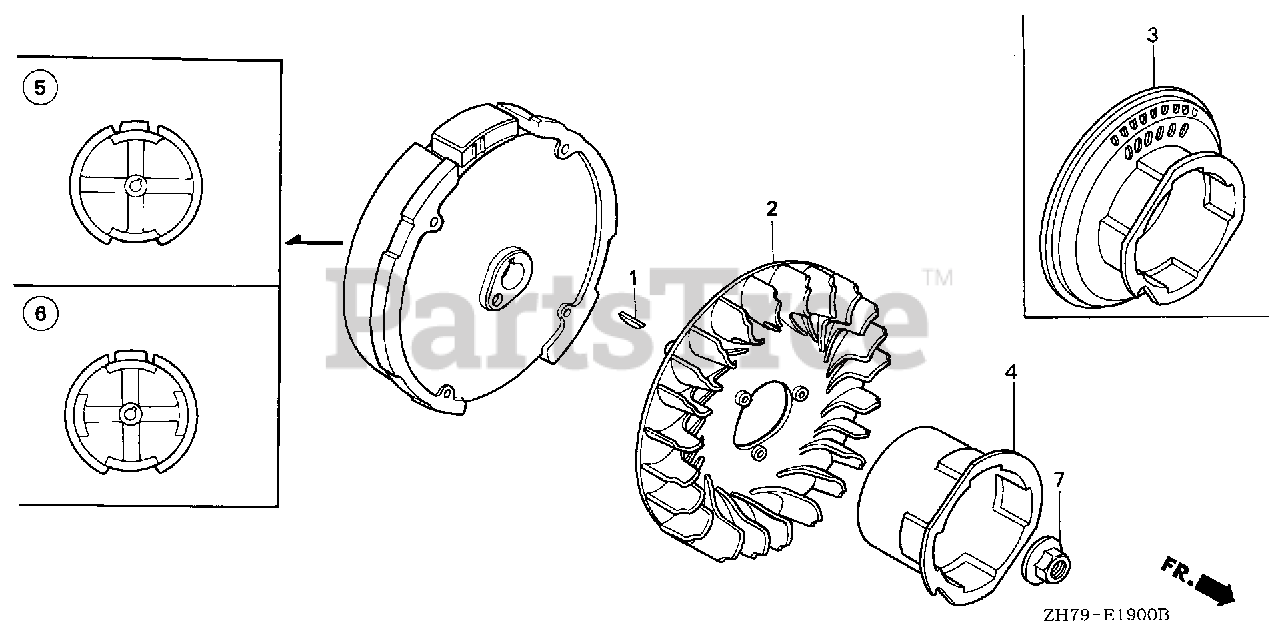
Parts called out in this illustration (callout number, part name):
1	KEY, SPECIAL WOODRUFF (25X18)
2	FAN, COOLING
4	PULLEY, STARTER
5	FLYWHEEL
7	NUT, SPECIAL (14MM)
